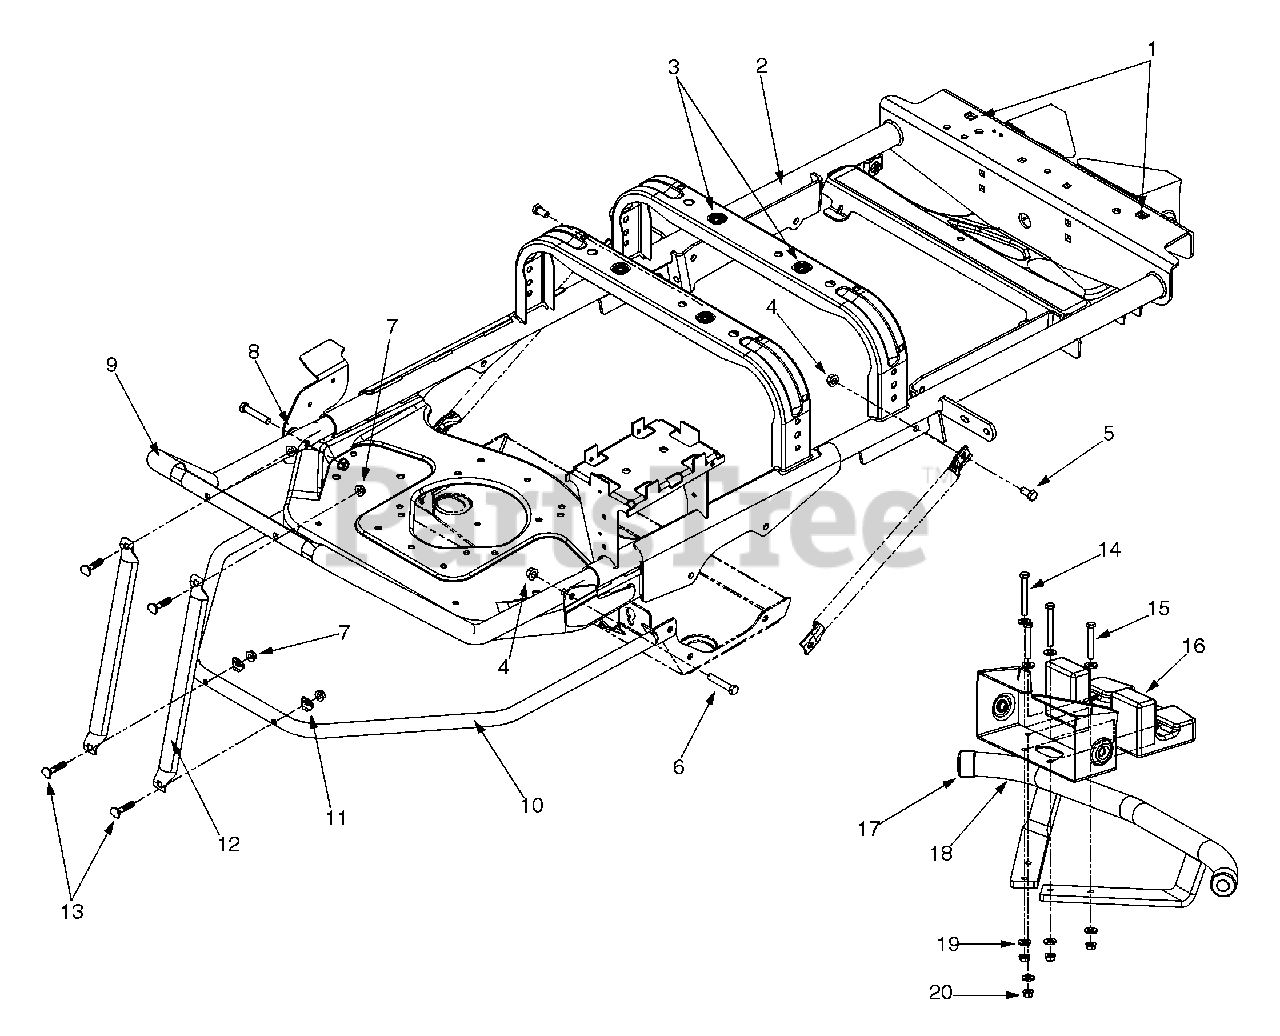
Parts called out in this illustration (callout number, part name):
1	Retainer Nut 3/8-16
2	Frame Assembly
3	Retainer Nut 3/8-16
4	Flange Lock Nut 3/8-16
5	Hex Cap Screw 3/8-16 x .75
6	Hex Cap Screw 3/8-16 x 2.0
7	Flange Lock Nut 5/16-18
8	Flat Washer .385 x 1.0 x .135
14	Hex Cap Screw 3/8-16 x 3.0
15	Hex Cap Screw 3/8 - 16 x 2.5
18	Bumper Ass'y
19	Flat Washer .406 ID x .875 OD
20	Flange Lock Nut 3/8-16
